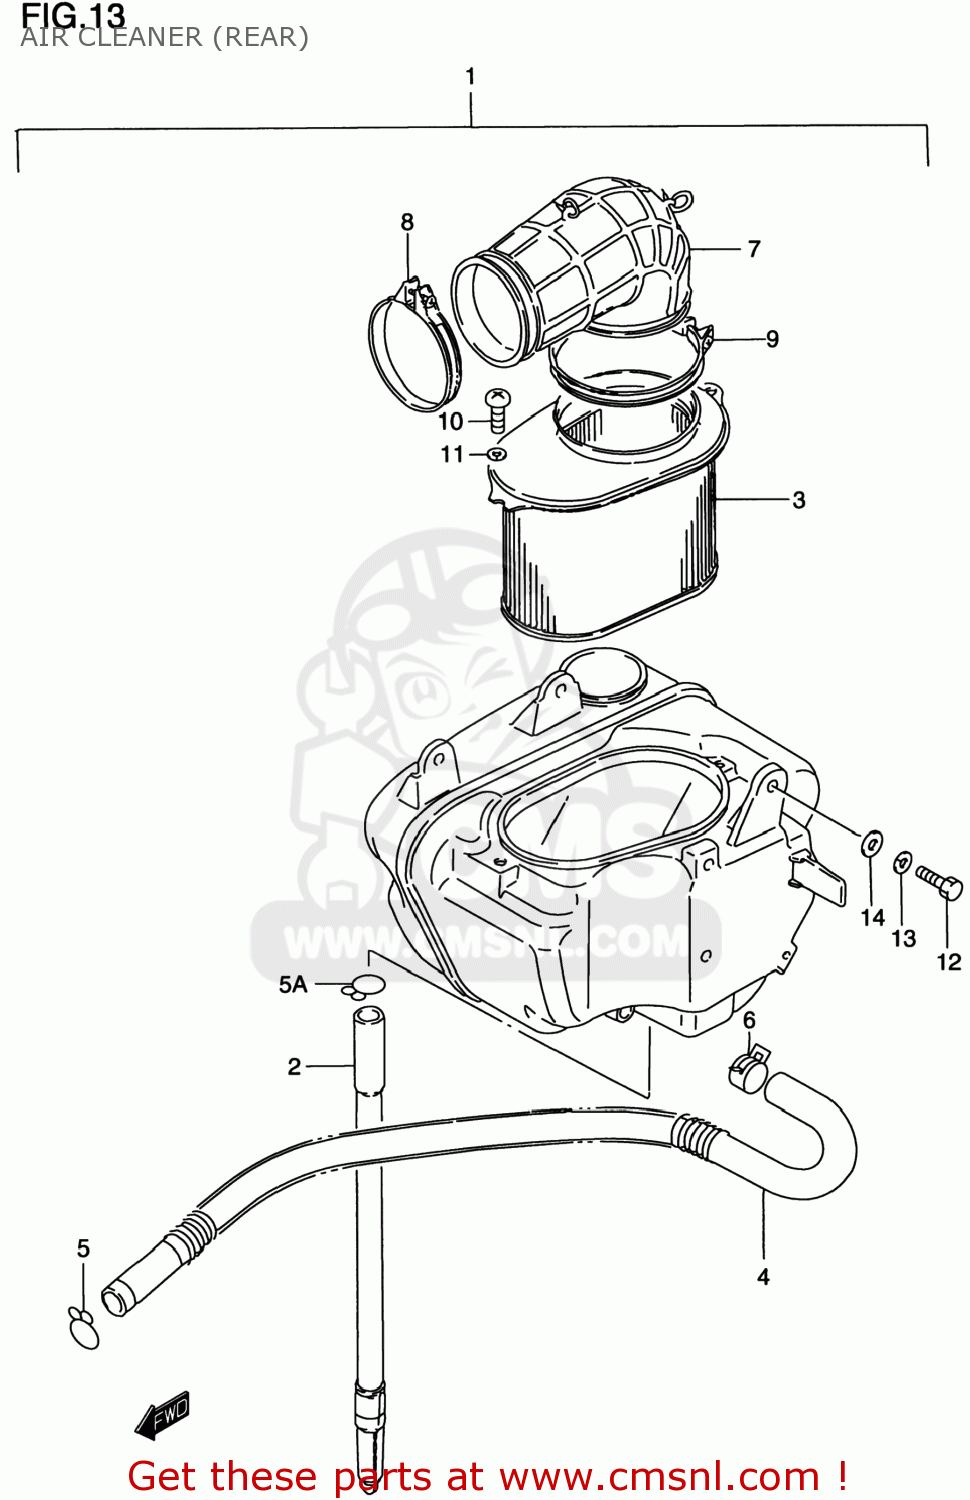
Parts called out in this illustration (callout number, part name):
1	CLEANER ASSY,AIR RR
2	TUBE,DRAIN
3	FILTER ASSY
4	TUBE SET,BREATHER
5	CLIP
5A	CLIP
6	CLIP
7	TUBE,AIR CLEANER OUTLET
8	CLAMP
9	CLAMP
10	SCREW
11	LOCK,WASHER
12	BOLT
13	WASHER,LOCK
14	WASHER(6.5X16X1.2)
